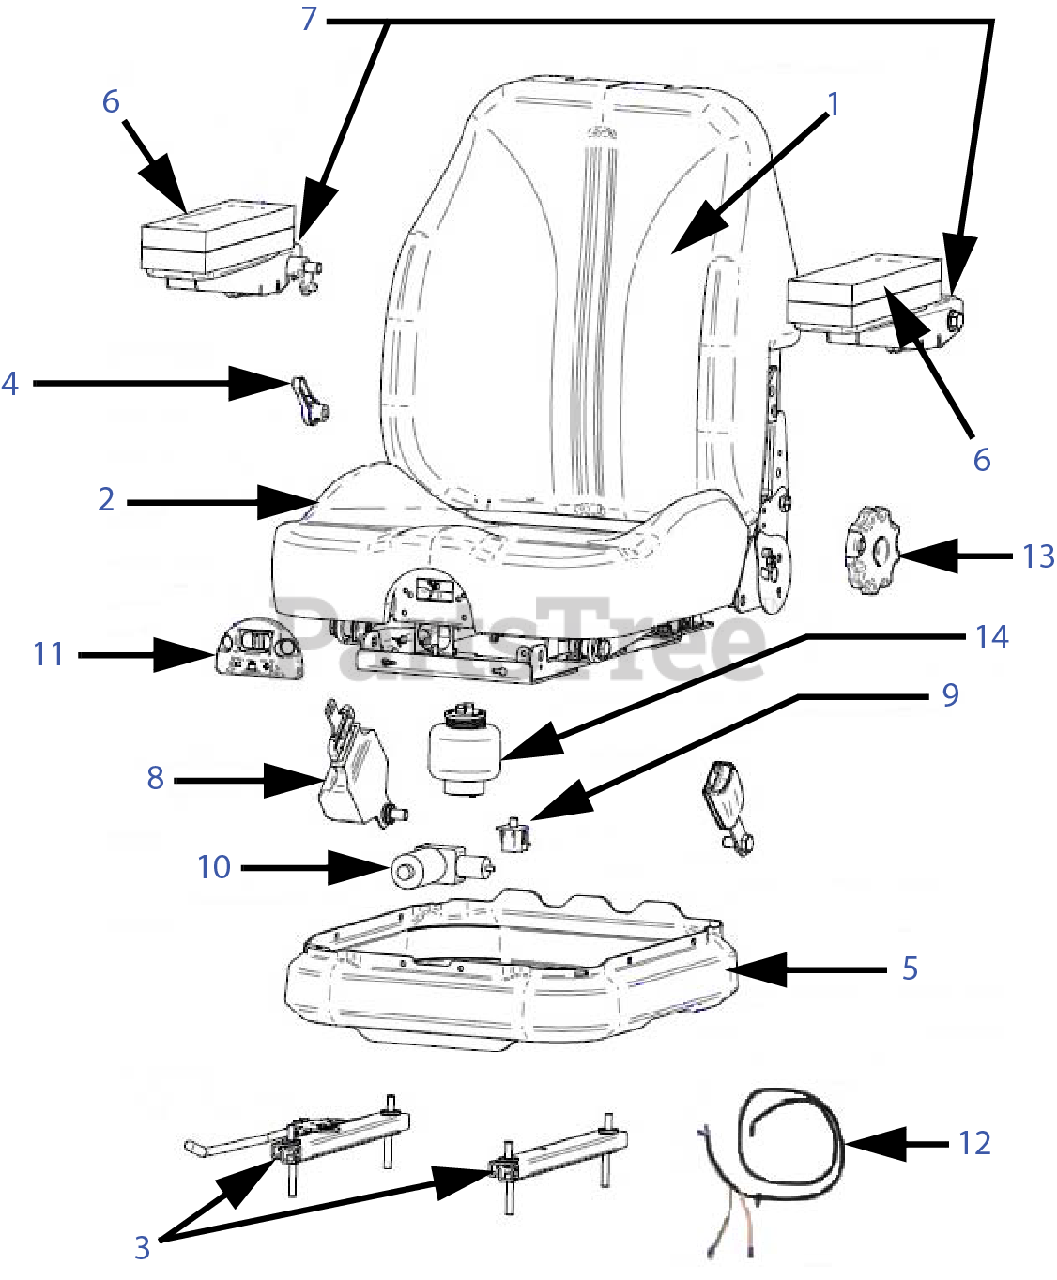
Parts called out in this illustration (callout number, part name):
1	BACK COVER WITH LOGO
3	7" SINGLE LOCKING TRACK - 1.75"
4	ISO LEVER W/ROLL P
5	BELLOWS-W/HARDWARE
6	SET OF ARM PADS
7	SET OF FRONT ADJUST ARMS PADDED
8	2" RETRACTABLE SEAT BELT KIT
9	PLUNGER SWITCH NC/NC
10	AIR COMPRESSOR KIT
11	HOSE KIT WITH AIR VALVE
12	AIR COMPRESSOR HARNESS
13	SEAT KNOB KIT
